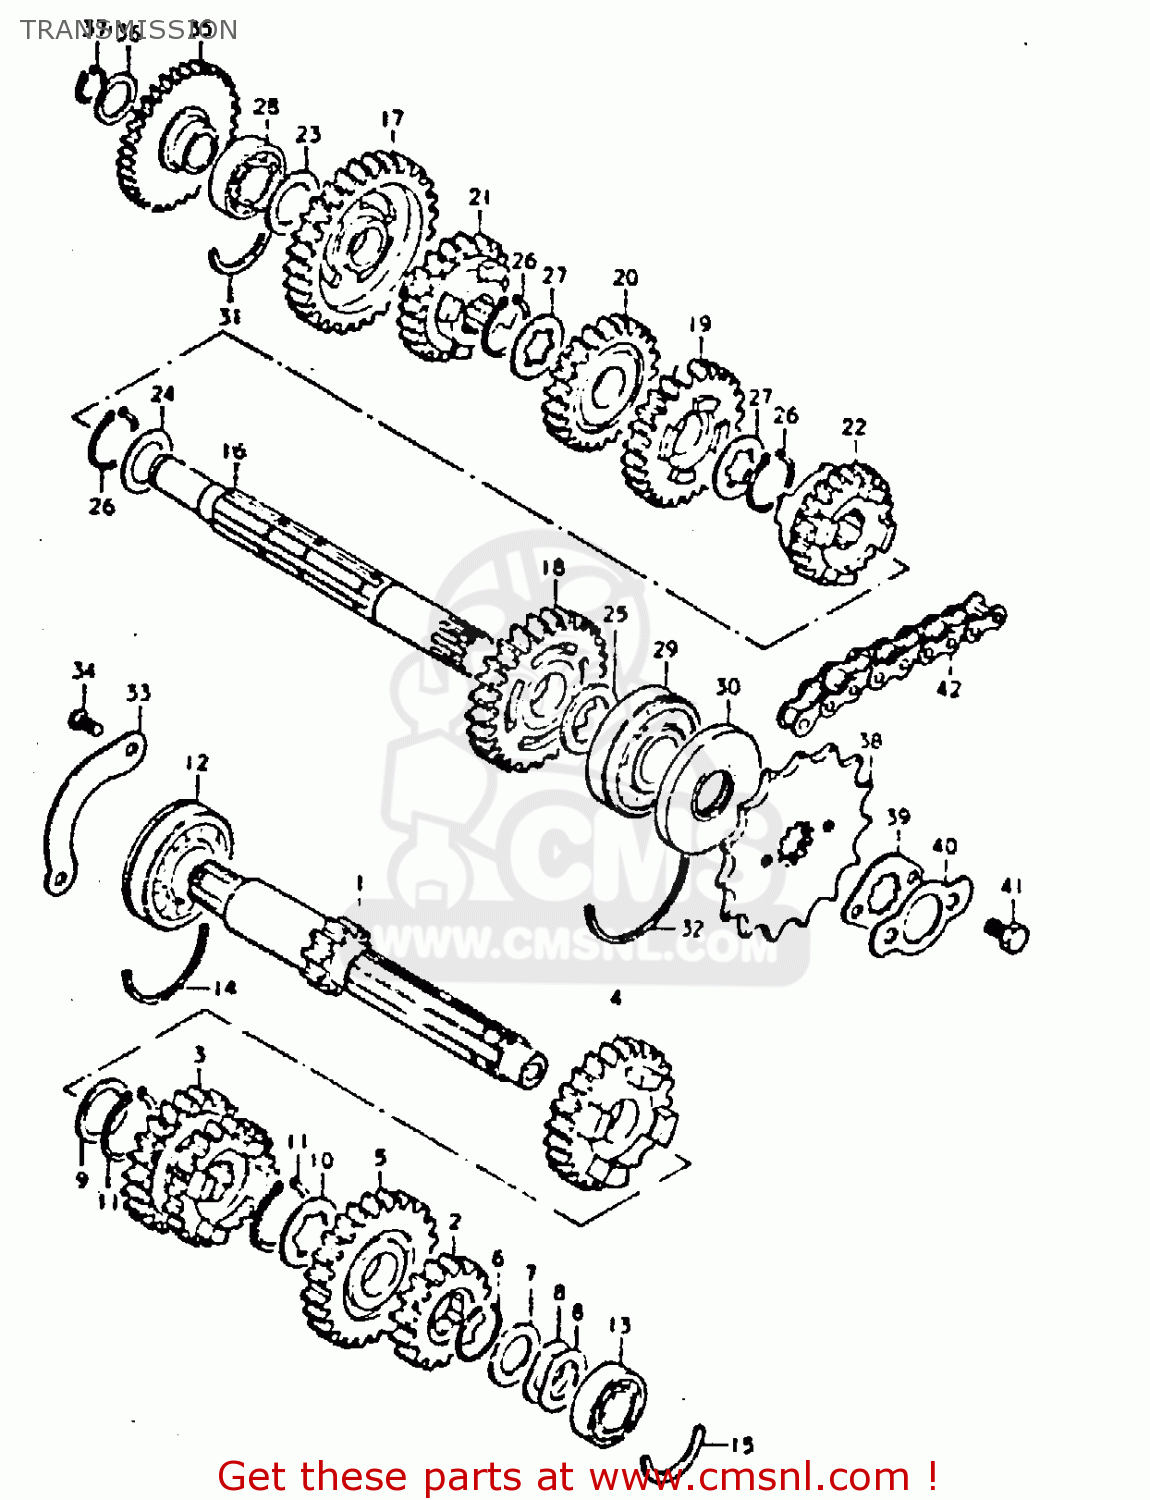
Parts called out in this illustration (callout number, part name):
1	SHAFT, COUNTER (NT:12)
2	GEAR,SECOND DRIVE
3	GEAR,THIRD/FOURTH DRIVE
4	GEAR,FIFTH DRIVE
5	GEAR,SIXTH DRIVE
6	CIRCLIP
7	WASHER (15X26X1.5)
8	WASHER
9	SHIM
10	WASHER,LOCK
11	CIRCLIP
12	BEARING
13	BALL BEARING
14	C RING
15	C RING
16	SHAFT,DRIVE
17	GEAR,FIRST DRIVEN
18	GEAR,SECOND DRIVEN
19	GEAR, 3RD DRIVEN (NT:23)
20	GEAR,FOURTH DRIVEN
21	GEAR,FIFTH DRIVEN
22	GEAR,SIXTH DRIVEN
23	WASHER,THRUST
24	SHIM
25	WASHER
26	CIRCLIP
27	WASHER,LOCK
28	BALL BEARING
29	BEARING
30	SEAL,OIL (20X52X7)
31	C RING
32	C RING
33	RETAINER, BEARING
34	SCREW 6X12
35	GEAR, KICK STARTER IDLER
36	WASHER,THRUST
37	CIRCLIP,15MM
38	SPROCKET,ENGINE(NT:15)
39	PLATE,ENGINE SPROCKET
40	LOCK WASHER
41	BOLT
42	CHAIN, DRIVE (520*102L)
